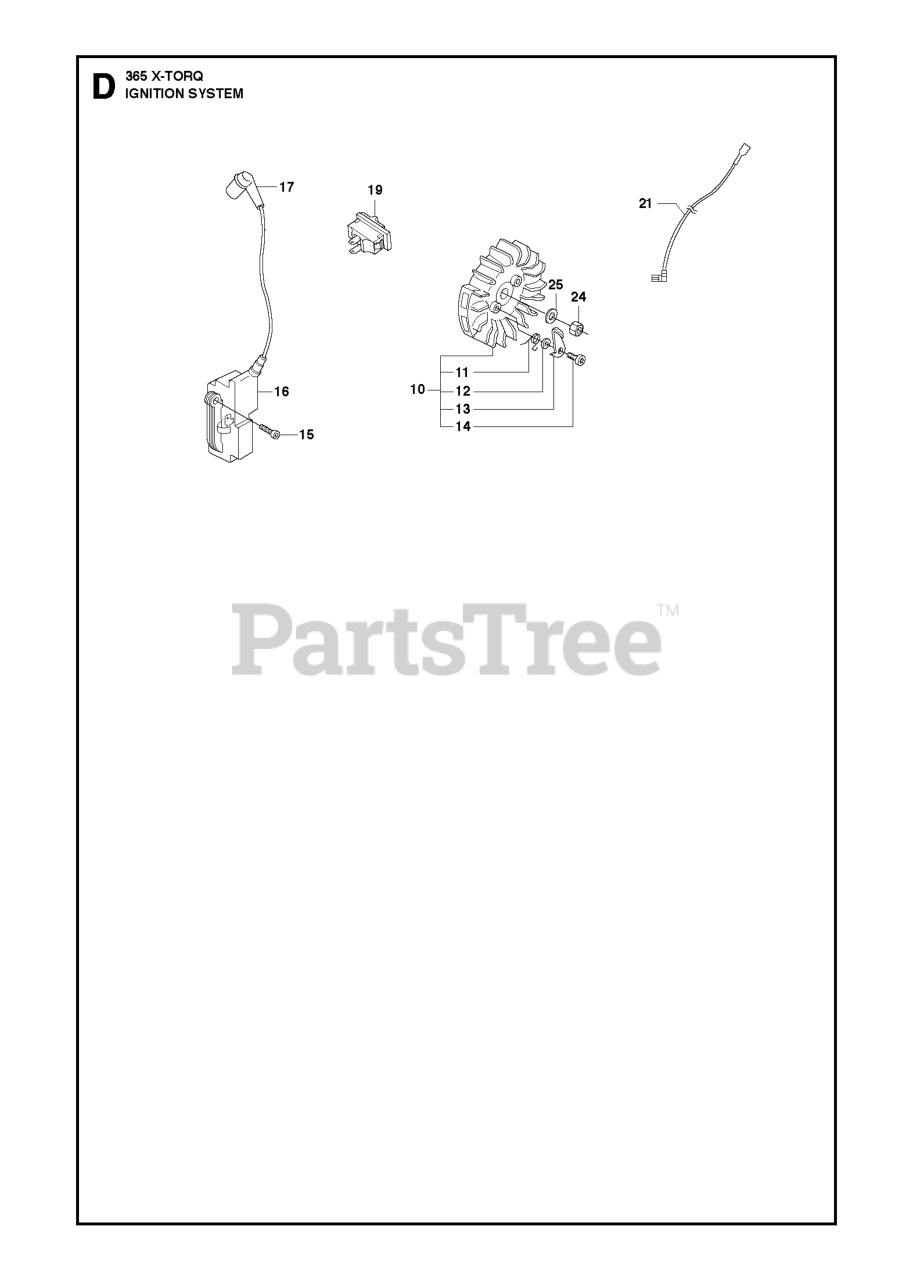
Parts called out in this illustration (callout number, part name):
14	SCREW
15	SCREW ITXSCM M5X20 T27 12.9 T
16	IGNITION MODULE
17	SPARK PLUG CONN. KIT
19	START/STOP SWITCH
25	WASHER 8.4X16
